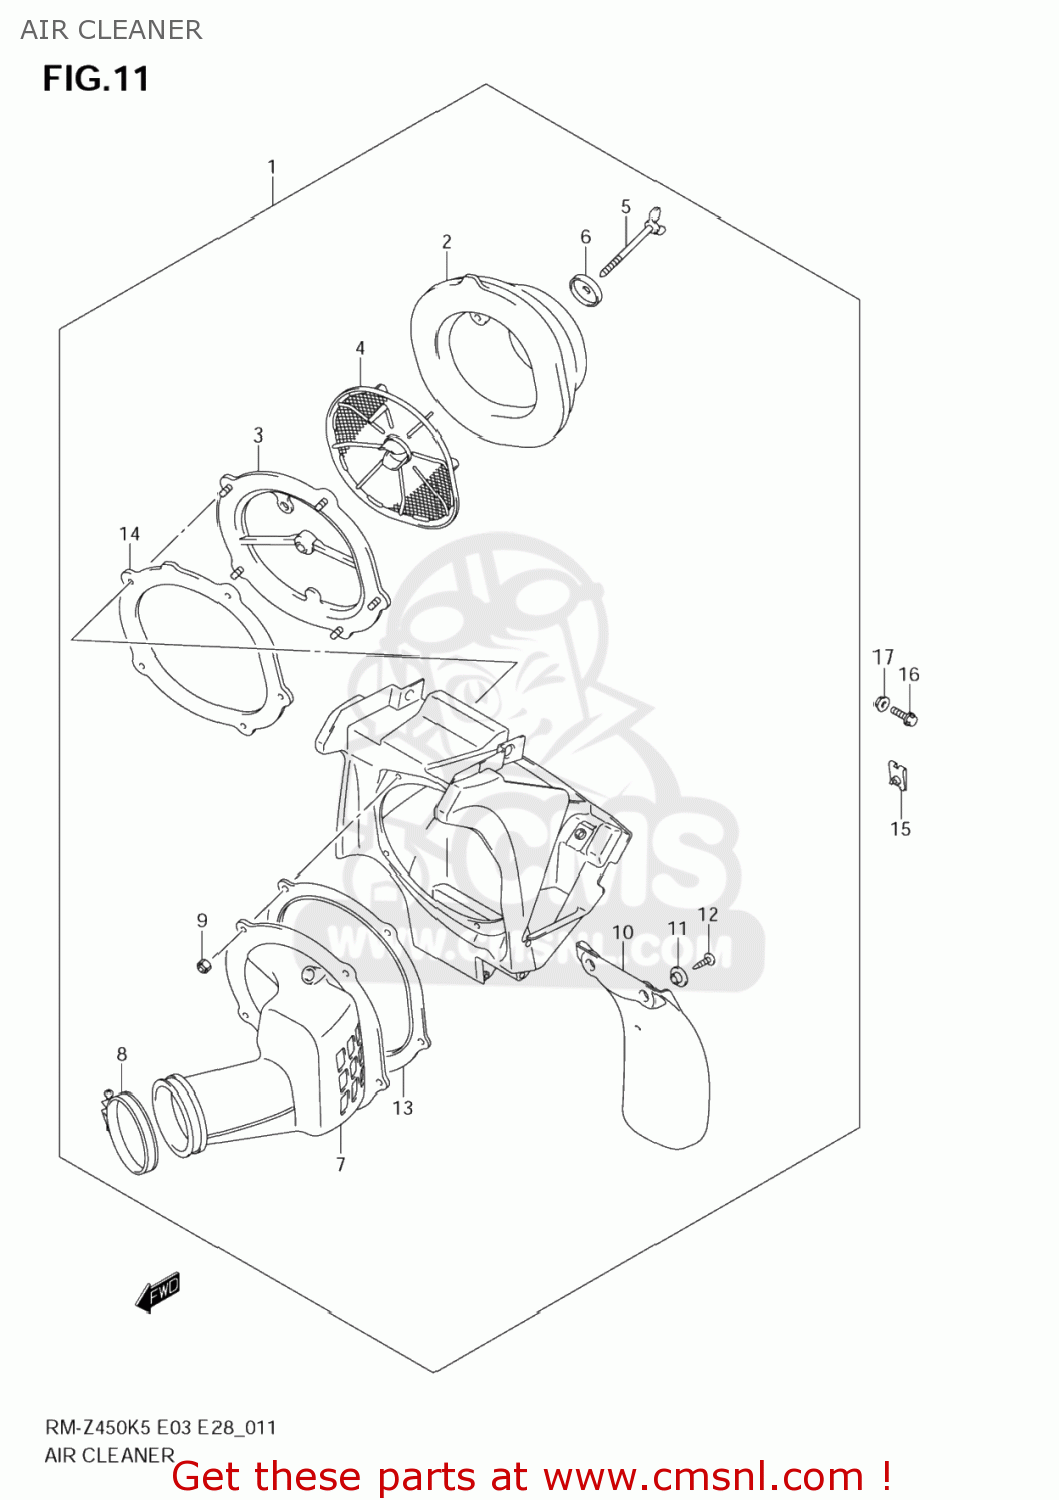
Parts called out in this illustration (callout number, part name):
1	CLEANER ASSY,AIR
2	FILTER ASSY
3	BASE,FILTER
4	HOLDER,FILTER
5	BOLT,WING
6	WASHER,AIR CLEANER
7	TUBE,OUTLET
8	CLAMP
9	NUT
10	MUDGUARD
11	COLLAR
12	SCREW
13	PLATE
14	GASKET (NAS)
15	HOLDER,REAR BU
16	BOLT(6X16)
17	WASHER,RR BRAK
